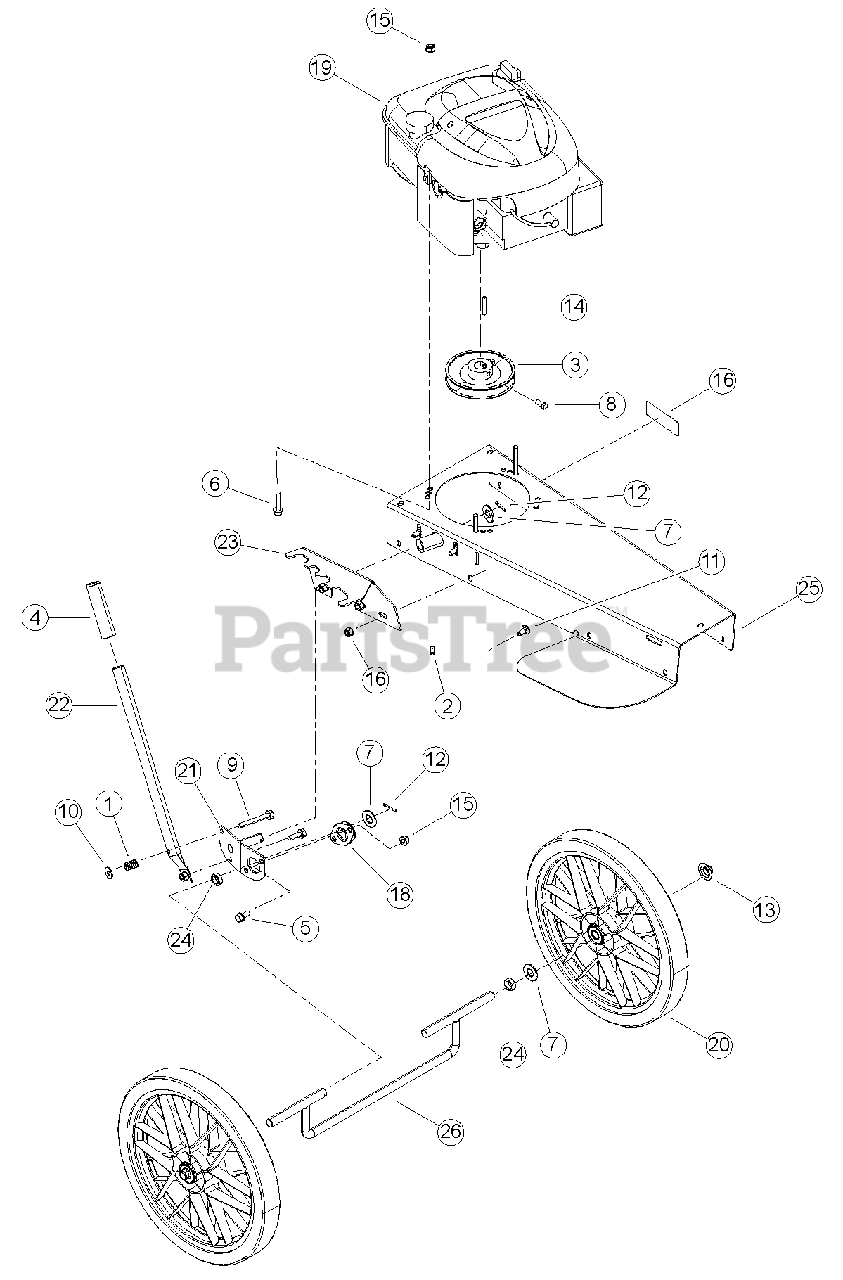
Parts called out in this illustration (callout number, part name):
1	SPRING, HEAVY DUTY COMPRESSION
2	FITTING, 1/4 SELF-TAP GREASE
3	PULLEY, 5.0 X 7/8 AB
4	GRIP, TILT CONTROL
5	BOLT, 5/16 X 3/4 FLANGE NC
6	BOLT, 5/16 X 1-1/2 FLANGE NC
7	WASHER, 5/8" SAE FLAT ZP
8	SCREW, 5/16-18 X 5/8 SQ HD SET
9	BOLT, 5/16 X 2-1/2 FLANGE NC
10	WASHER, 5/16" FLAT ZP
11	BOLT, 5/16X3/4 GR5 NC ZP CRG
12	PIN, 1/8 X 1.00 ZP COTTER
13	PUSHNUT, 5/8" ZP
14	KEY, SQUARE 3/16"*1-1/2"LG PLN
15	NUT, 5/16-18 NYLOCK-FLANGE
16	DECAL, SERIAL NUMBER
17	ANTI-SEIZE LUBRICANT 8 OZ BRUSH TOP BTL
18	BEARING, SIDE FLNG MOUNT, 5/8"
19	ENGINE, 6.5 HP QUANTUM HD 50 STATE (FOR SERVICE SEE ENGINE OWNER'S MANUAL OR YOUR NEAREST AUTHORIZED BRIGGS & STRATTON INDUSTRIAL ENGINE DEALER.)
20	WHEEL, 15 INCH TRIMMER (BLACK)
21	WELDMENT, AXLE PIVOT
22	HANDLE, TRIMMER HEIGHT ADJUST
23	PLATE, HANDLE LOCK
24	SPACER, 7/8 X .281
25	WELDMENT, TRIMMER BODY
26	WELDMENT, TRIMMER AXLE
